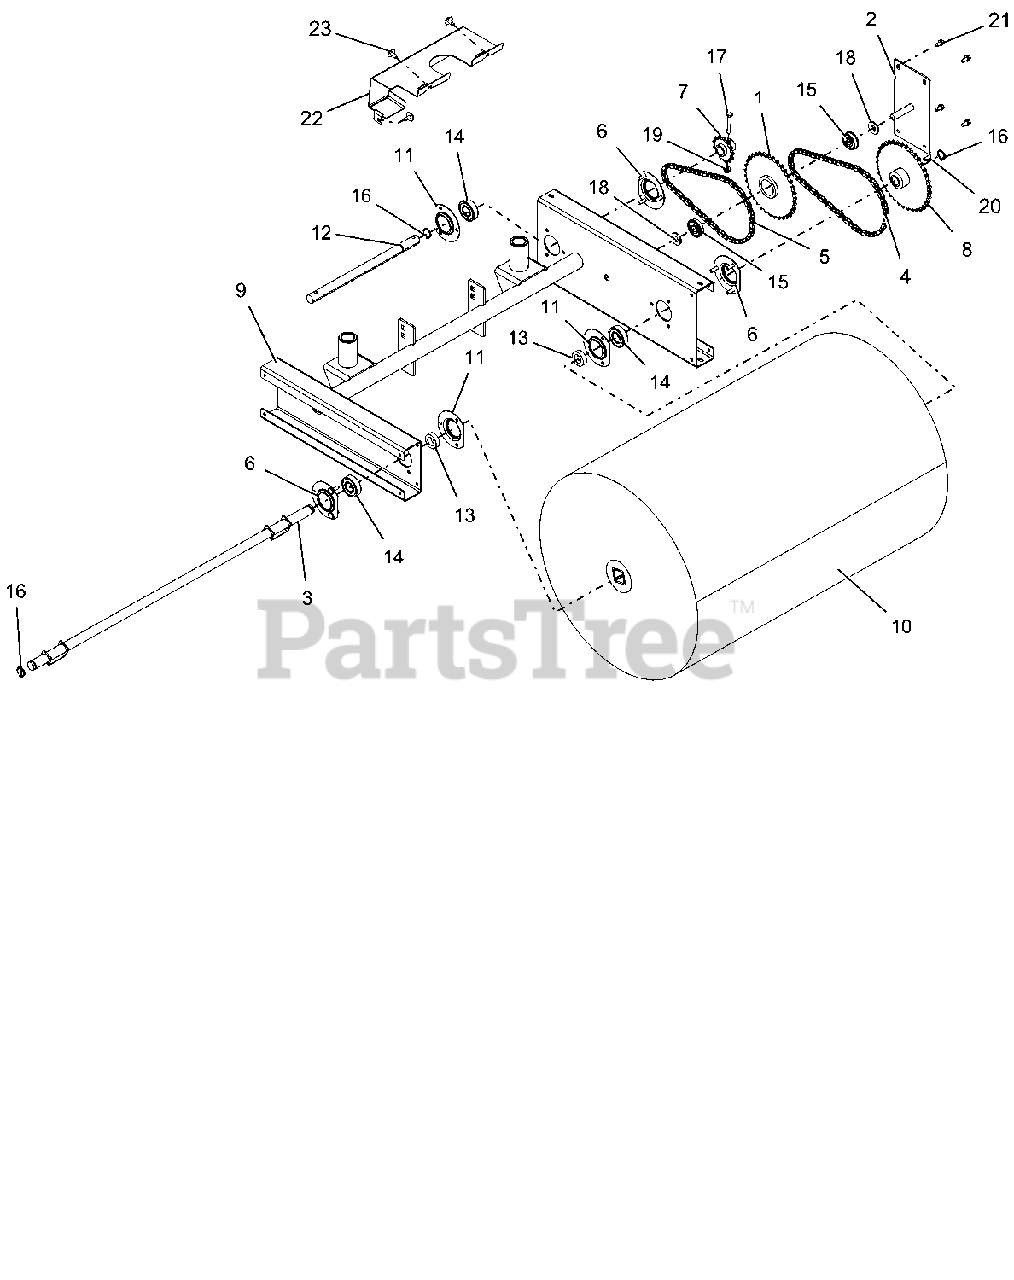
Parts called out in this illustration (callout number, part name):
1	SPROCKET, REDUCTION IDLER
2	MOUNT, REDUCTION IDLER (ORANGE)
3	SHAFT, 28" BRUSH
4	CHAIN, #40-54 LINKS
5	CHAIN, #41-50 LINKS
6	FLANGE, BEARING
7	SPROCKET, DRIVE
8	SPROCKET, DRIVEN
9	FRAME, POWER BROOM-DELUXE (BLACK)
10	BRUSH, 18" DIA X 28" WIDE
11	FLANGE, BEARING
12	SHAFT, TRANSMISSION
13	SPACER, .755x1.250x.370
14	BRG-BALL .750X1.750X.50
15	BRG, BALL .501 X 1.38 X .438 SEALED
16	RG-RTNG-EXT .750x.078
17	BLT-HEX .25-20X1.75 GR5 YWZC
18	WSHR-FL-STL .536X1.070X.109 YWZC
19	NUT, LK-TOP-FLG .25-20 YWZC
20	KEY, WDRF - .188X.75X.313 REV
21	SCR-TAP .25-20X.50 HWH TR YWZ
22	COVER, FRONT SHAFT - CE (BLACK)
23	SCR, TAP .25-20X.50 LGHWH TR
